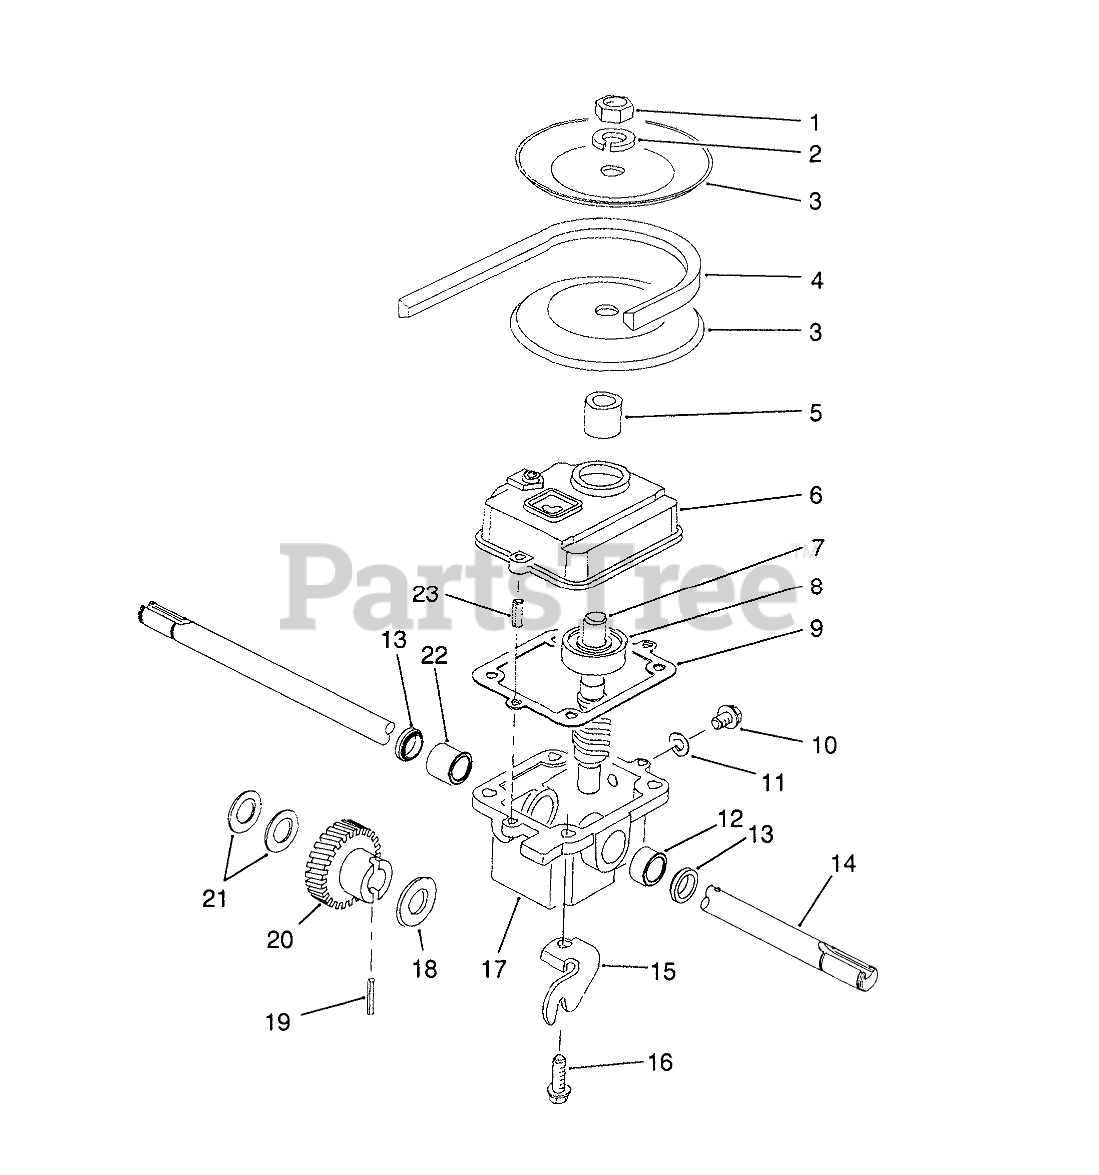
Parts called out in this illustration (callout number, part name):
1	NUT-JAM
2	WASHER-LOCK
3	PULLEY-DRIVEN HALF
4	V-BELT
5	SPACER - PULLEY
6	GEAR CASE COVER
7	SHAFT - WORM
8	BEARING
9	GASKET
10	NYLON SCREW
11	FILL PLUG GASKET
12	BUSHING
13	SEAL-OIL
14	OUTPUT SHAFT
15	TRACTION BRACKET
16	SCREW-HWHTF
17	GEAR CASE
18	THRUST WASHER
19	PIN-SPRING
20	GEAR - HELICAL
21	WASHER-PLAIN
22	BUSHING
23	3/16 X 1/2 ROLL PIN
